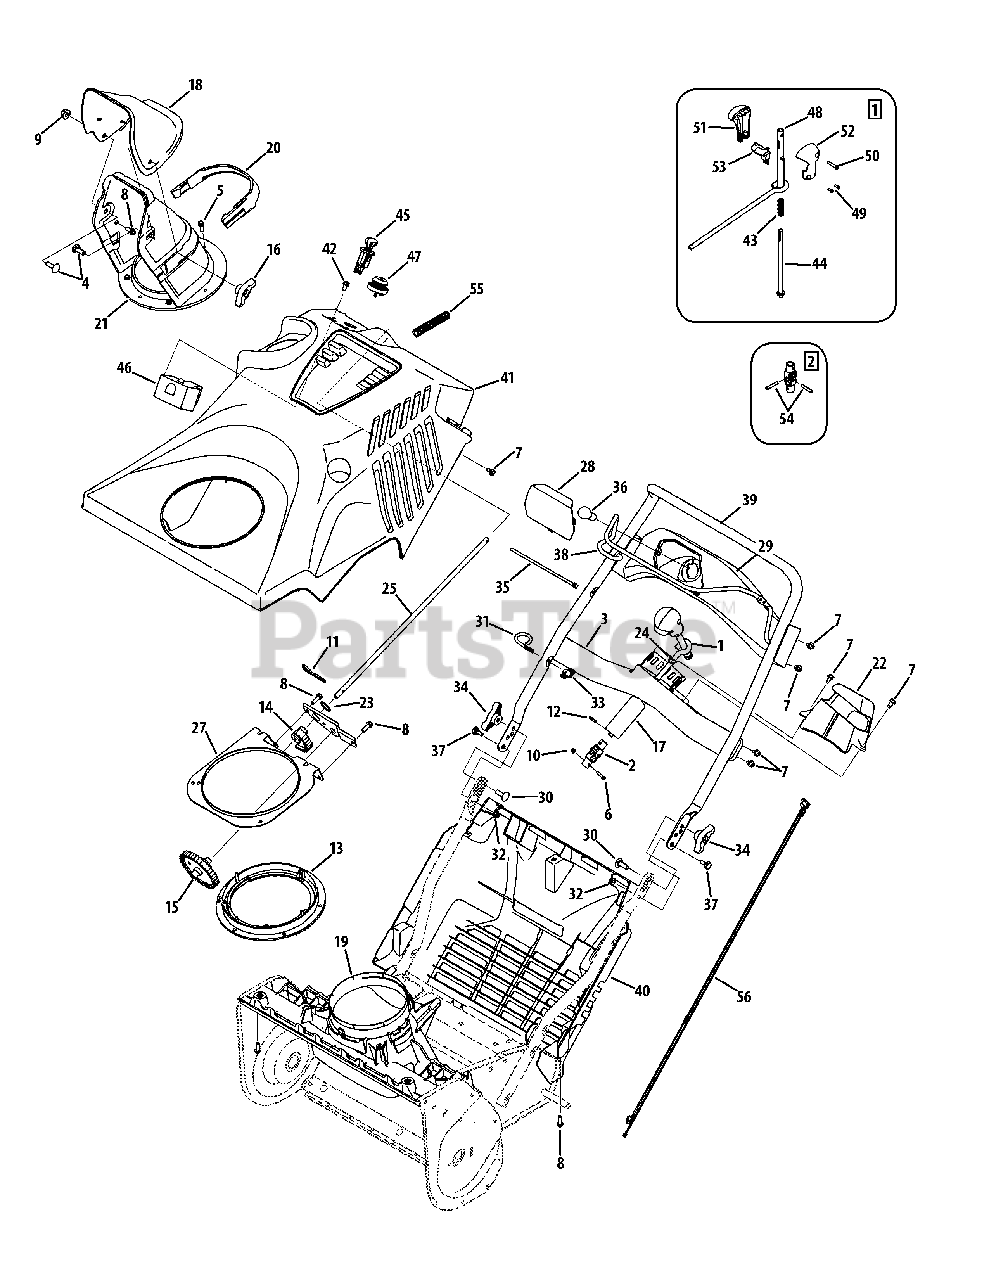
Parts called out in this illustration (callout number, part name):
1	Chute Rotation Control Assembly
2	Joint Block Assembly
3	Indicator Bracket Assembly
4	Carriage Bolt, 5/16-18 x .750
5	Hex Washer Screw, 1/4 x .750
6	Machine Screw, #8-32 x .88
7	Hex Washer Screw, 1/4-20 x 0.500
8	Hex Washer Screw, 1/4-15 x 0.750
9	Flange Lock Nut, 5/16-18
10	Hex Lock Nut, #8-32
11	Cotter Pin, .125 x 2.5
12	Spring Pin, .156 x .85
13	Bevel Gear, 95T
14	Spur Gear, 35T
15	Spur Gear, 40T/11T
16	Wing Knob, 5/16-18
17	Grip, 1.18 x 3.33
18	Upper Chute
19	Chute Adapter
20	Chute Plug
21	Lower Chute
22	Chute Rotation Cover
23	Flat Washer, .75 x 1.00 x .06
24	Plastic Bushing, .380
25	Chute Rotation Rod, 3/8
26	Gear Mounting Plate
27	Gear Retainer Bracket
28	Handle Panel Lens
29	Handle Panel
29	Light Label
30	Carriage Screw, 5/16-18 x 1.00
31	Eye Bolt, 1/4-20
32	Flange Lock Nut, 1/4-20
33	Wing Knob, 1/4-20
34	Wing Knob, 5/16-18
35	Cable Tie, 3/16 x .05 x 7.4
36	Lamp, #1141
37	Shoulder Screw, 1/4-20 x .375 x .148
38	Auger Control
39	Upper Handle
40	Bottom Cover Assembly
41	Cover Assembly
42	Hex Washer Screw, 1/4-15 x .50
43	Compression Spring, .460 x 1.469
44	Chute Rotation Rod
45	Ignition Switch Assembly
46	Electric Starter
48	Chute Rotation Rod Assembly
49	Screw, #6 x .375
50	Screw, #8 x 1.00
51	RH Control Knob
52	LH Control Knob
53	Joystick Trigger
54	Roll Pin, 3/16 x 1.1
55	Conduit
56	Wiring Harness w/ Light Socket
